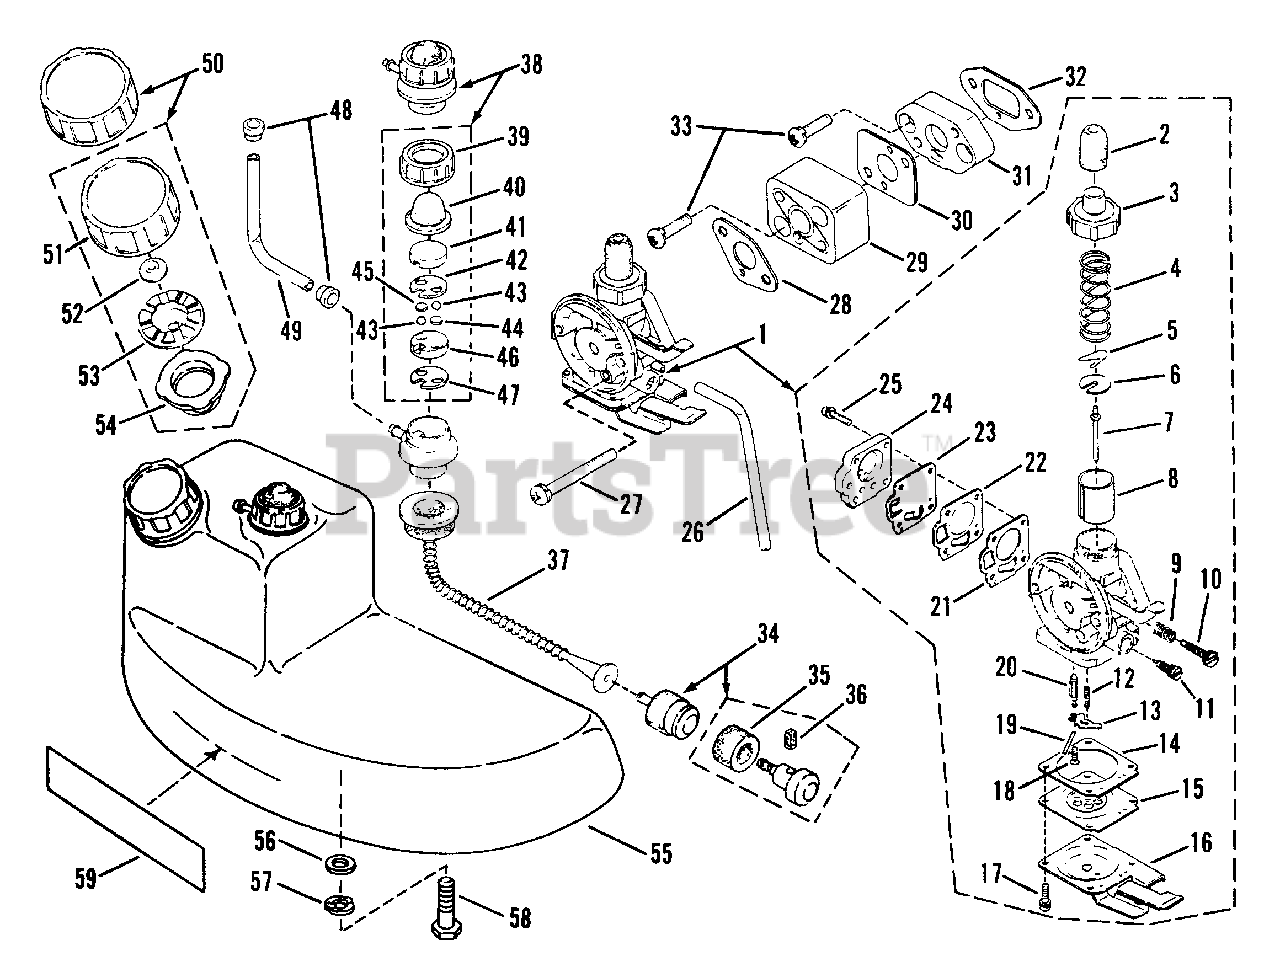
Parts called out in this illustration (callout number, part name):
1	CARBURETOR ASSM'Y.
2	CAP, Rubber
3	CAP, Mixing Chamber
4	SPRING, Throttle
5	CLIP, Needle
6	RETAINER, Spring
7	NEEDLE, Jet Assembly
8	VALVE, Throttle
9	SPRING, Throttle Adj. Screw
10	SCREW, Throttle Adj.
11	NEEDLE, Main Jet Assm'y.
12	SPRING, Inlet Valve
13	ARM, Float
14	GASKET, Main Diaphragm
15	DIAPHRAGM, Main Assm'y.
16	COVER, Main Diaphragm
18	SCREW, Float Pin Set
19	PIN, Float
20	VALVE, Float
21	GASKET, Pump Cover
22	VALVE, Pump Check
23	DIAPHRAGM, Pump
26	TUBE, Overflow
27	SCREW, Carburetor
28	GASKET, Carburetor
29	INSULATOR, Intake
30	GASKET, Insulator
31	FLANGE, Intake
32	GASKET, Flange
34	FILTER ASSM'Y., Fuel
37	HOSE, Fuel
38	PRIMER PUMP ASSM'Y.
39	CAP, Pump
40	CAP, Rubber
41	SEAT, Valve B
46	SEAT, Valve A
48	CLIP, Fuel Tube
49	TUBE, Fuel
50	CAP ASSM'Y., Fuel
51	CAP, Fuel
54	GASKET
55	TANK, Fuel
56	WASHER, Flat
57	WASHER/SPRING, M6
58	BOLT, M6 x 16mm
59	DECAL, SNAPPER
